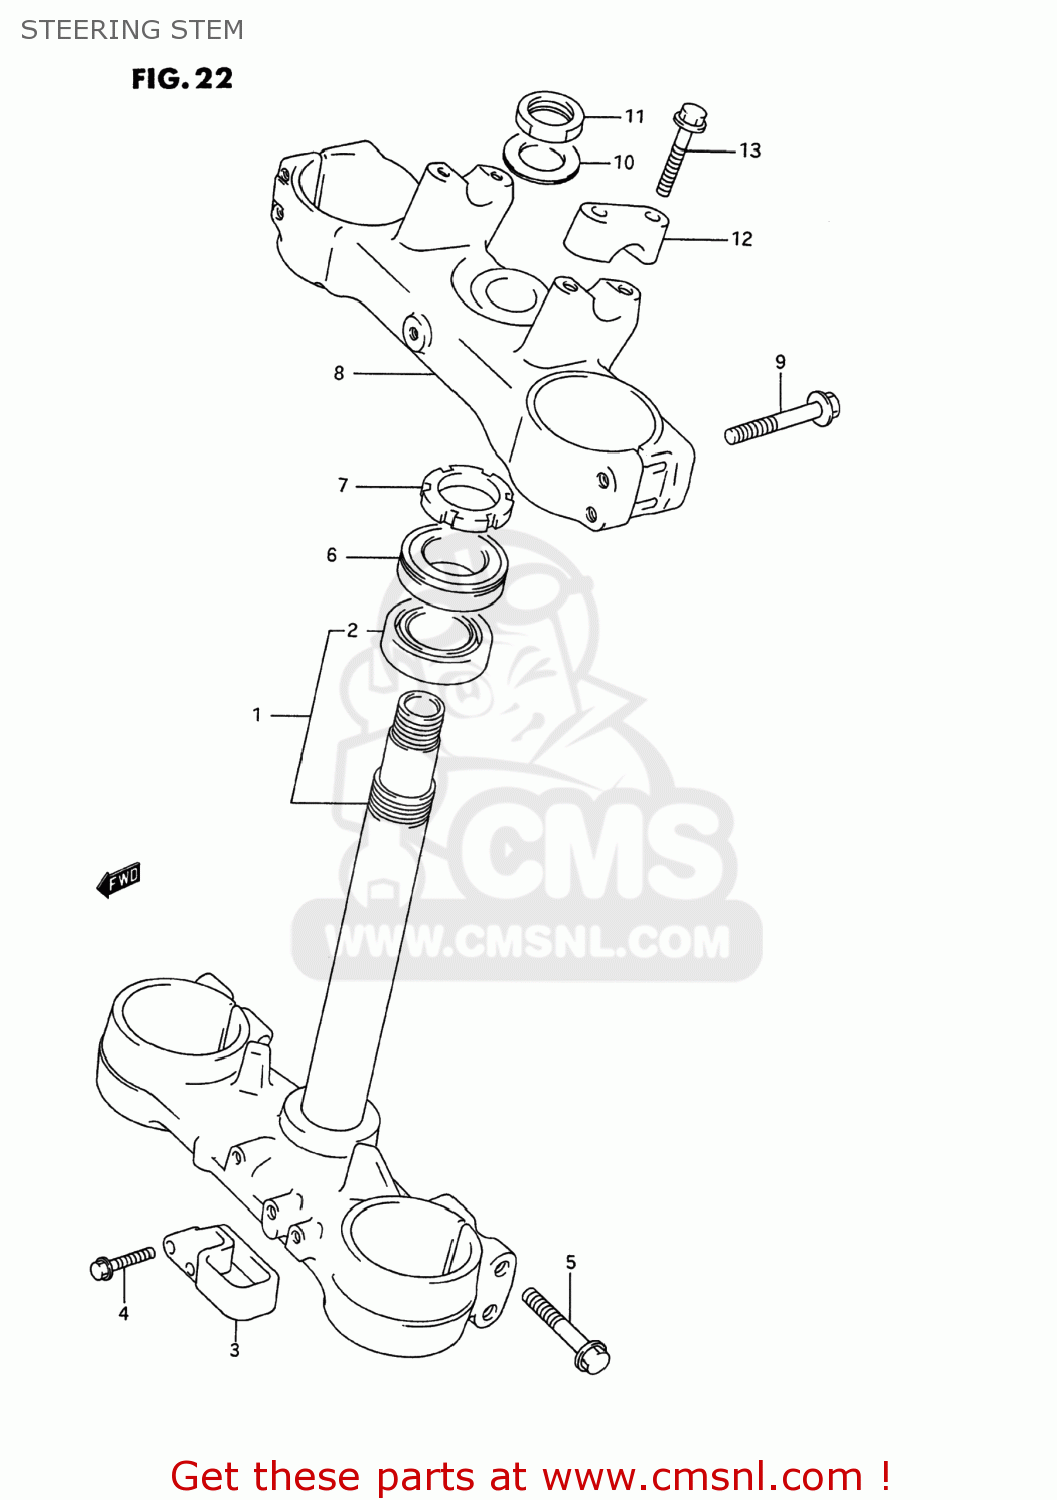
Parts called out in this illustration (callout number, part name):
1	STEM,STEERING
2	BEARING(30X52X16)
3	GUIDE,HOSE
4	BOLT
5	BOLT
6	BEARING(30X52X16)
7	NUT,STEERING
8	HEAD,STEERING STEM
9	BOLT
10	WASHER,STEM HEAD
11	NUT,STEM HEAD
12	HOLDER,HANDLEBAR
13	BOLT
